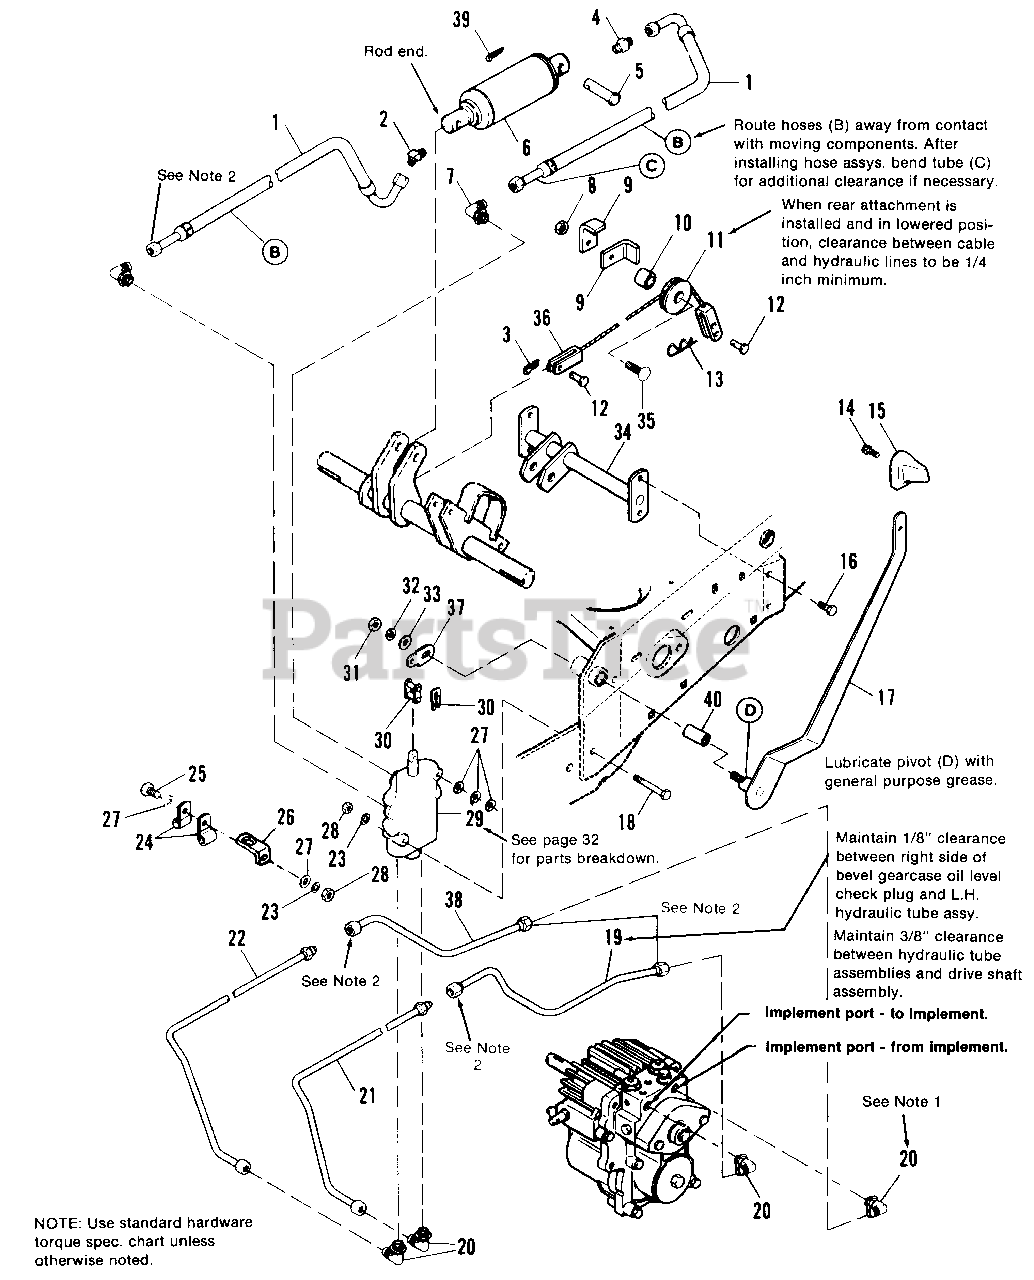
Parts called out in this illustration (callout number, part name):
1	HOSE, Hydraulic
2	ELBOW, 45ø Male
3	PIN, Cotter, 3/32 x 1
4	CONNECTOR, 37ø Male
6	CYLINDER, Hydraulic
7	ELBOW, Adjustable, 37ø
8	LOCKNUT, Hex, Jam, 3/8-16
9	GUARD, Cable
13	CLIP, Spring
14	SCREW, Hex, Was. Hd., Taptite, 1/4-20 x 1-1/4
16	SCREW, Hex, Wash. Hd., Taptite, 3/8-16 x 3/4
17	LEVER ASSY.
18	CAPSCREW, Hex Hd., 1/4-20 x 2-1/4
20	ELBOW, Adjustable, 37ø
23	LOCKWASHER, 1/4
25	CAPSCREW, Hex Hd., 1/4-20 x 1-1/4
27	WASHER, Plain, 1/4
28	NUT, Hex, Full, 1/4-20
29	CONTROL VALVE ASSY. (See page 32)
30	LINK, Connecting
31	NUT, Hex, Full, 3/8-16
32	LOCKWASHER, 3/8
33	WASHER, Plain, 3/8
34	SUPPORT ASSY.
35	SCREW, Special
36	CABLE ASSY.
39	PIN, Cotter
